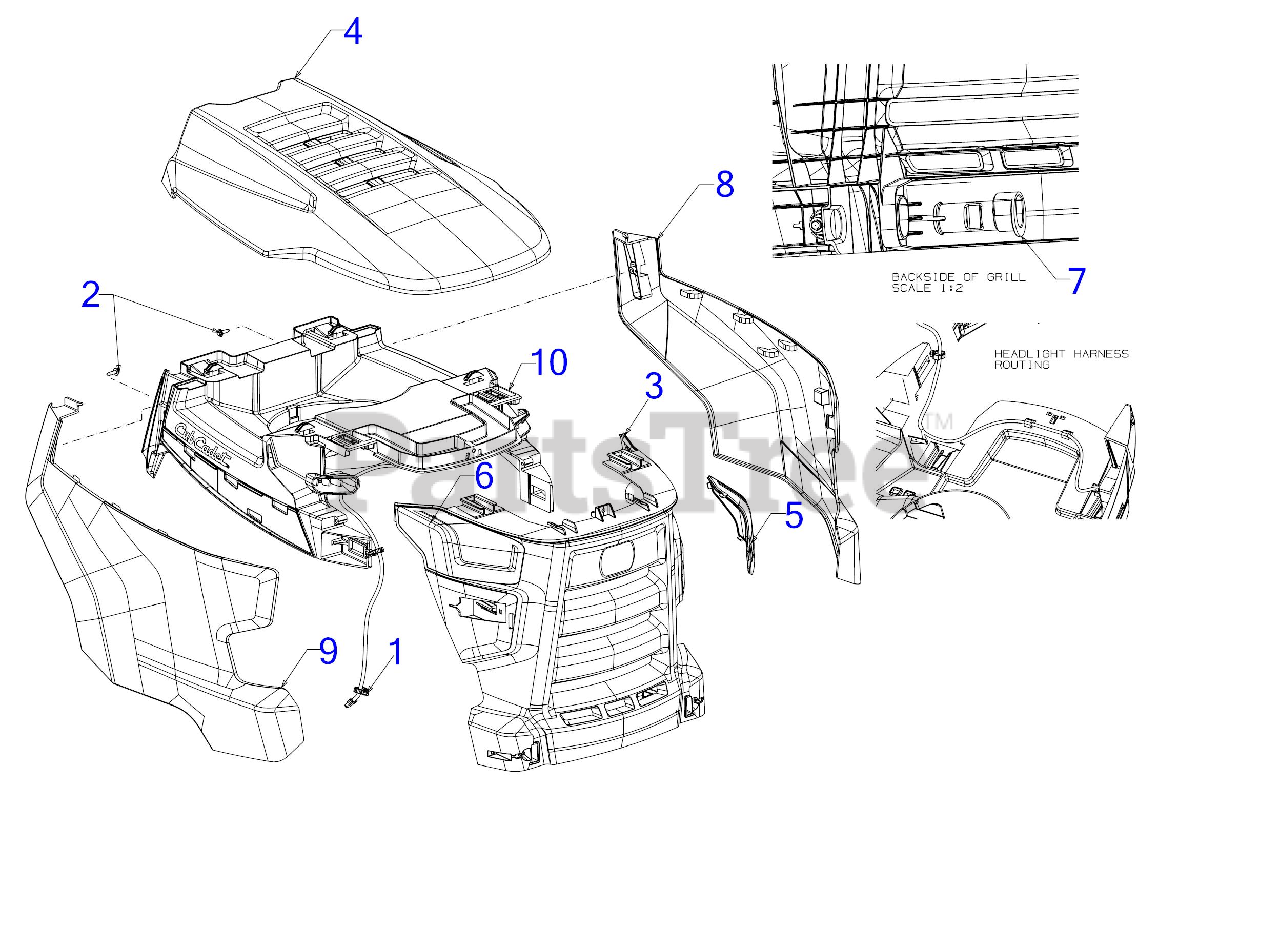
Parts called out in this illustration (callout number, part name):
1	HEADLIGHT HARNESS ASSEMBLY W/LED
2	SCREW 1/4-10 x .750
3	FRONT GRILLE (STYLE C)
4	HOOD TOP
5	HEADLIGHT LENS-LED
6	HEADLIGHT LENS-LED
7	HOOD PIVOT PIN
8	SIDE PANEL (LH)
9	SIDE PANEL (RH)
10	PLENUM/HOOD FRAME
